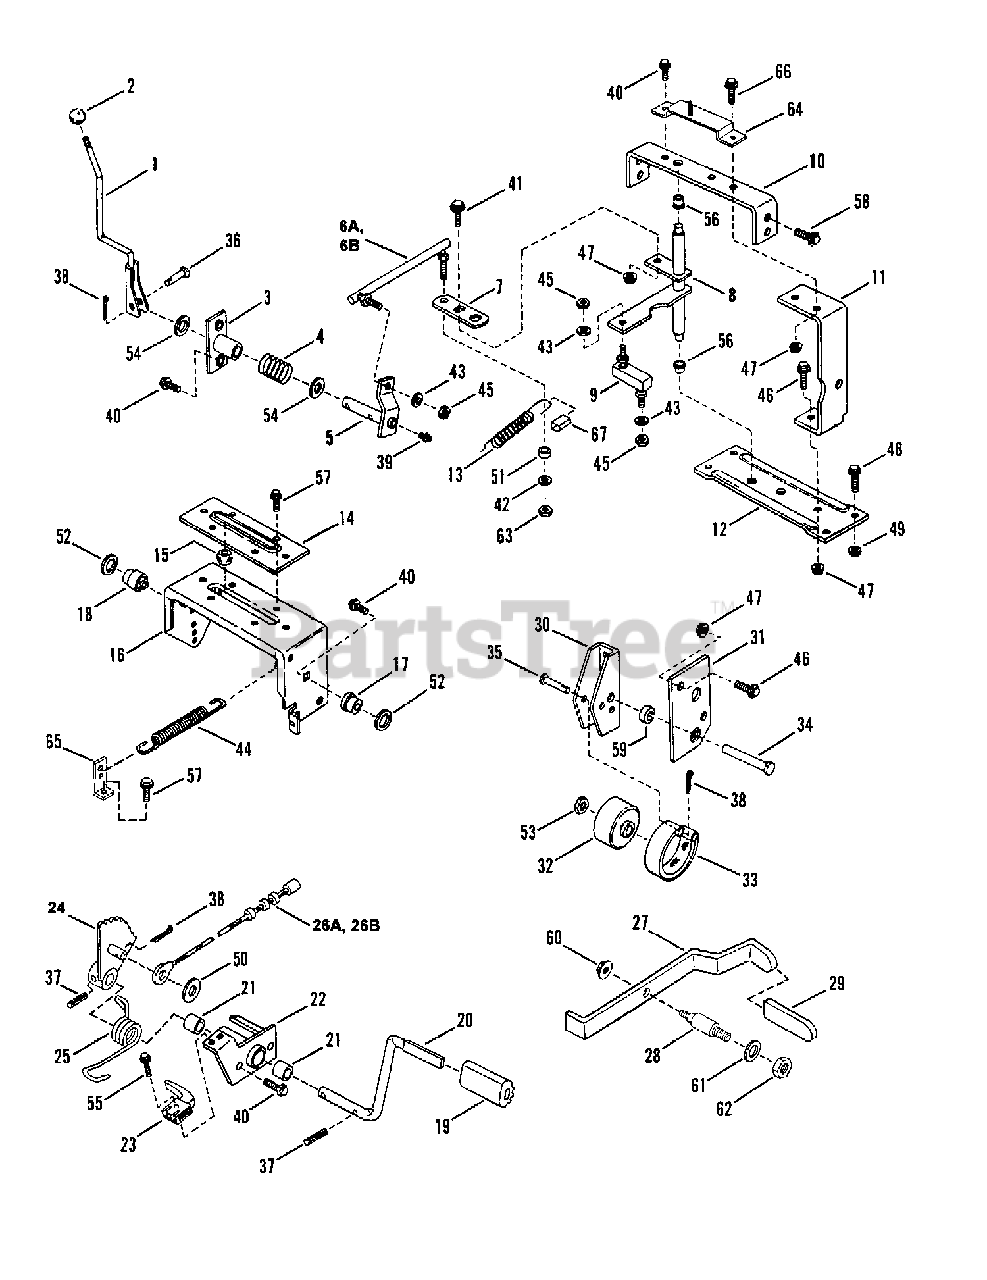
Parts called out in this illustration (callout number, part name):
1	SHIFTER, Transmission
2	KNOB, Shifter
3	PIVOT, Shift
4	SPRING, Shift Detent
5	ARM, Shifter
6A	LINK, Shift-Long (8.53")(84)(No longer available)
6B	LINK, Shift-Long (9.53")('85)
7	ARM, Shift Adjusting
8	ARM, Shift
9	LINK, Shift-Short
10	STRAP, Upper Cross
11	STRAP, Brake Pivot Support (No longer available)
12	STRAP, Lower Cross (No longer available)
13	SPRING, Reverse Assist (15 Coils)
14	RETAINER (PLATE), Clutch Yoke Bushing
15	BUSHING, Clutch Ball
16	YOKE, Clutch
17	BUSHING, Yoke Pivot-Short
18	BUSHING, Yoke Pivot-Long
19	PAD, Pedal
20	PEDAL, Clutch Brake
21	BEARING, Sleeve
22	BRACKET, Pedal Pivot
23	SWITCH, Clutch Interlock
24	ARM, Clutch/Brake
25	SPRING, Clutch/Brake
26A	CABLE, Clutch/Brake 1984 (34.54")
26B	CABLE, Clutch/Brake 1985 (35.54")
27	LEVER, Parking Brake
28	STUD, Parking Brake
29	SLEEVE, Parking Brake
30	LEVER, Brake Pivot
31	SUPPORT, Brake Pivot
32	DRUM, Brake
33	BAND, Brake
34	PIN, 3/8 x 2-9/16" Clevis
35	PIN, 1/4 x 1-13/16" Clevis
36	PIN, 3/8 x 1-1/4" Clevis
37	PIN, 3/16" x 1-1/4" Roll
38	PIN, 3/32 x 3/4" Cotter
39	FITTING, Lube
40	SCREW, 5/16-18 x 5/8" Hex Flange Self-Tap
41	BOLT, 5/16-18 x 5/8" Hex Flange Lock
42	WASHER, 5/16 SAE
43	WASHER, 5/16 Split Lock
44	SPRING
45	NUT, 5/16-24 Hex
46	BOLT, 5/16-18 x 3/4" Hex Flange Lock.
47	NUT, 5/16-18 Hex Flange Lock, Grade 5
48	BOLT, 3/8-16 x 3/4" Hex Flange Lock
49	NUT, 3/8-16 Hex Flange Lock
50	WASHER, 3/8 SAE Flat
51	ROLLER, Shift Arm
52	WASHER, Shim
53	JAM-NUT, 5/8-18
54	WASHER, Thrust
55	SCREW, #10-24 x1" Self-Tap
56	BEARING, Nylon
57	SCREW, 1/4-20 x 1/2" Hex Flange Self-Tap
58	SCREW, 3/8-16 Hex Flange Self-Tap
59	RING
60	NUT, 1/4-20 Small Flange Lock
61	WASHER, 3/8 Internal Tooth Lock
62	NUT, 3/8-16 Hex, Grade 5
63	NUT, 5/16-24 Hex Center Lock
64	STUD BRK'T ASS'Y
65	CLIP, Spring Attach
66	BOLT, 5/16-18 x 1" Hex Flange Lock
67	CLIP, Spring Retainer
